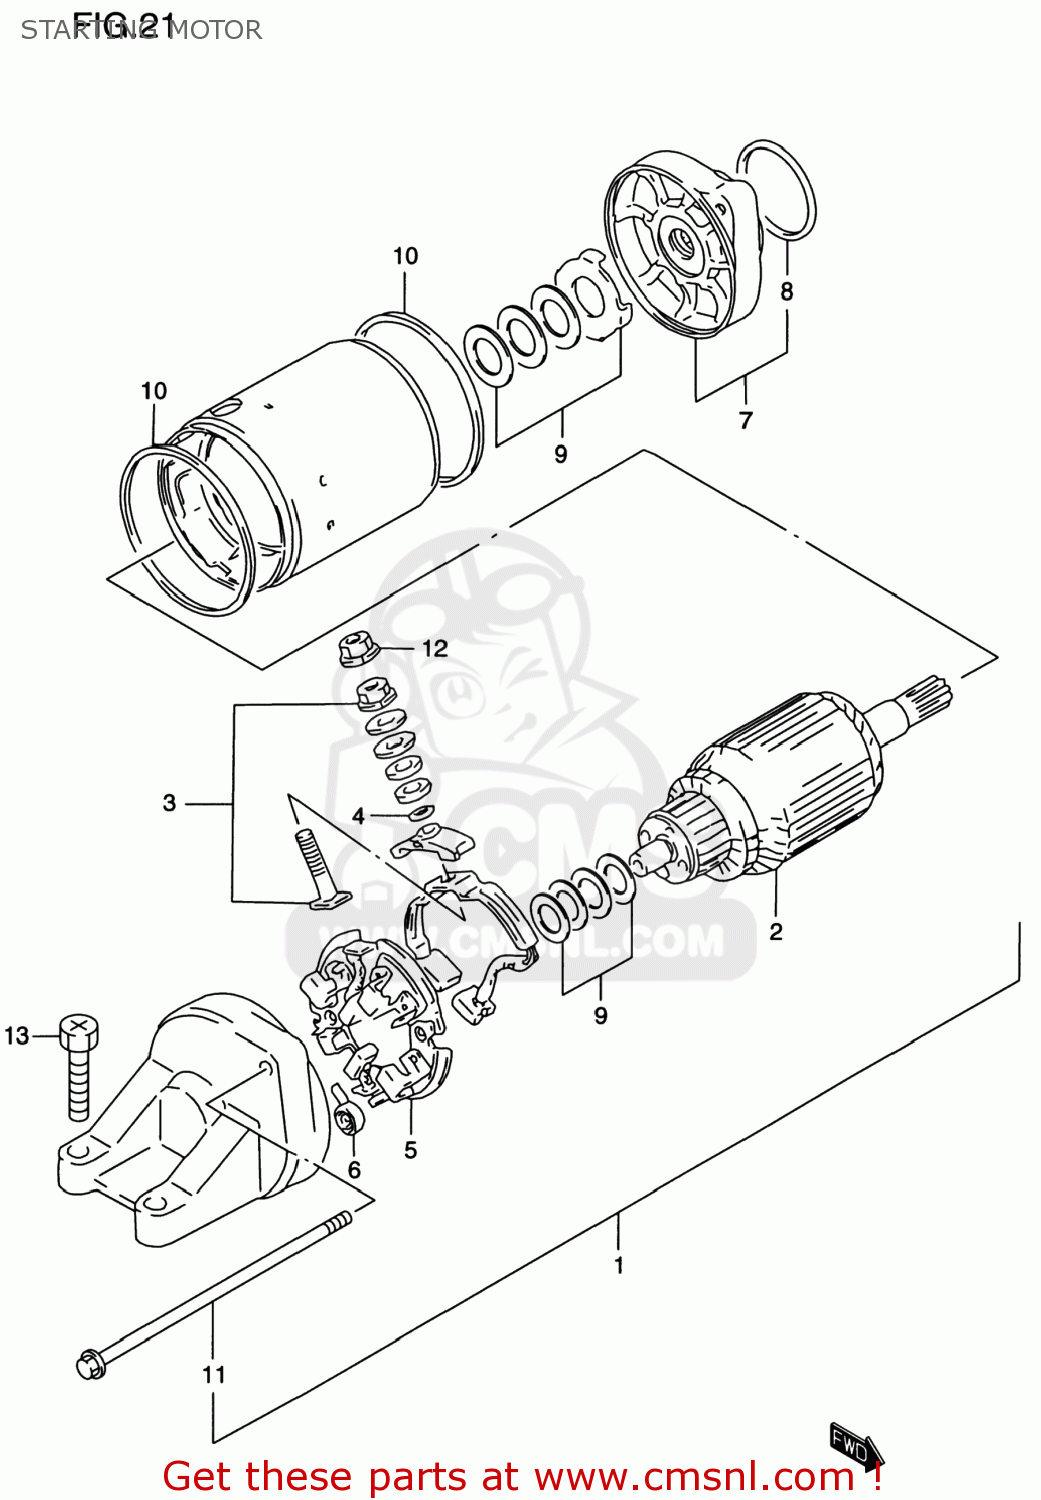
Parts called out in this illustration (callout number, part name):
1	MOTOR ASSY,STARTING
2	ARMATURE
3	TERMINAL SET,BRUSH
4	O RING
5	HOLDER SET,BRUSH
6	SPRING,BRUSH
7	BRACKET ASSY,FR
8	O RING
9	SHIM SET,STARTING MOTOR
10	O RING
11	BOLT
12	NUT
13	SCREW (6X25)
